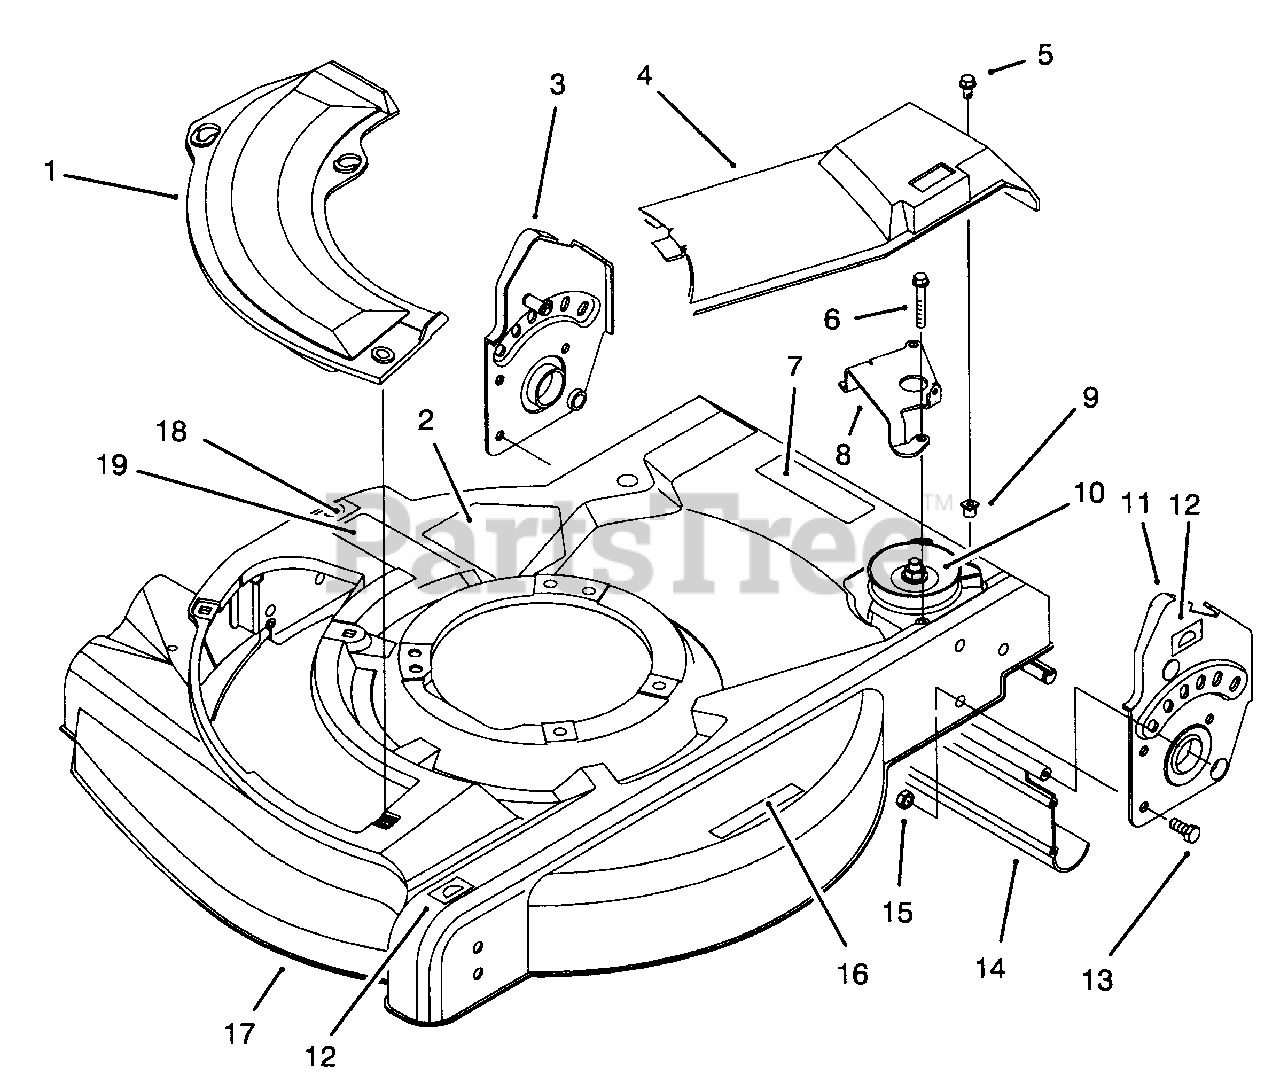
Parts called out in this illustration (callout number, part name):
1	Plate-Cover
2	Decal-Danger
3	Bracket-Handle R.H.
4	Cover-Drive
5	Screw-Phillips Hd.
6	Screw-Hex Hd. Cap
7	Decal-Warning
8	Guide-Transmission
9	Grommet
10	Gear Case Assembly
11	Bracket-Handle L.H.
12	Decal-H.O.C.
13	Screw-Hex Hd. Cap
14	Shield-Trailing
15	Nut-Lock
16	Decal-Warning
17	Housing & Baffle Assembly
18	Decal-H.O.C.
19	Decal-Discharge
